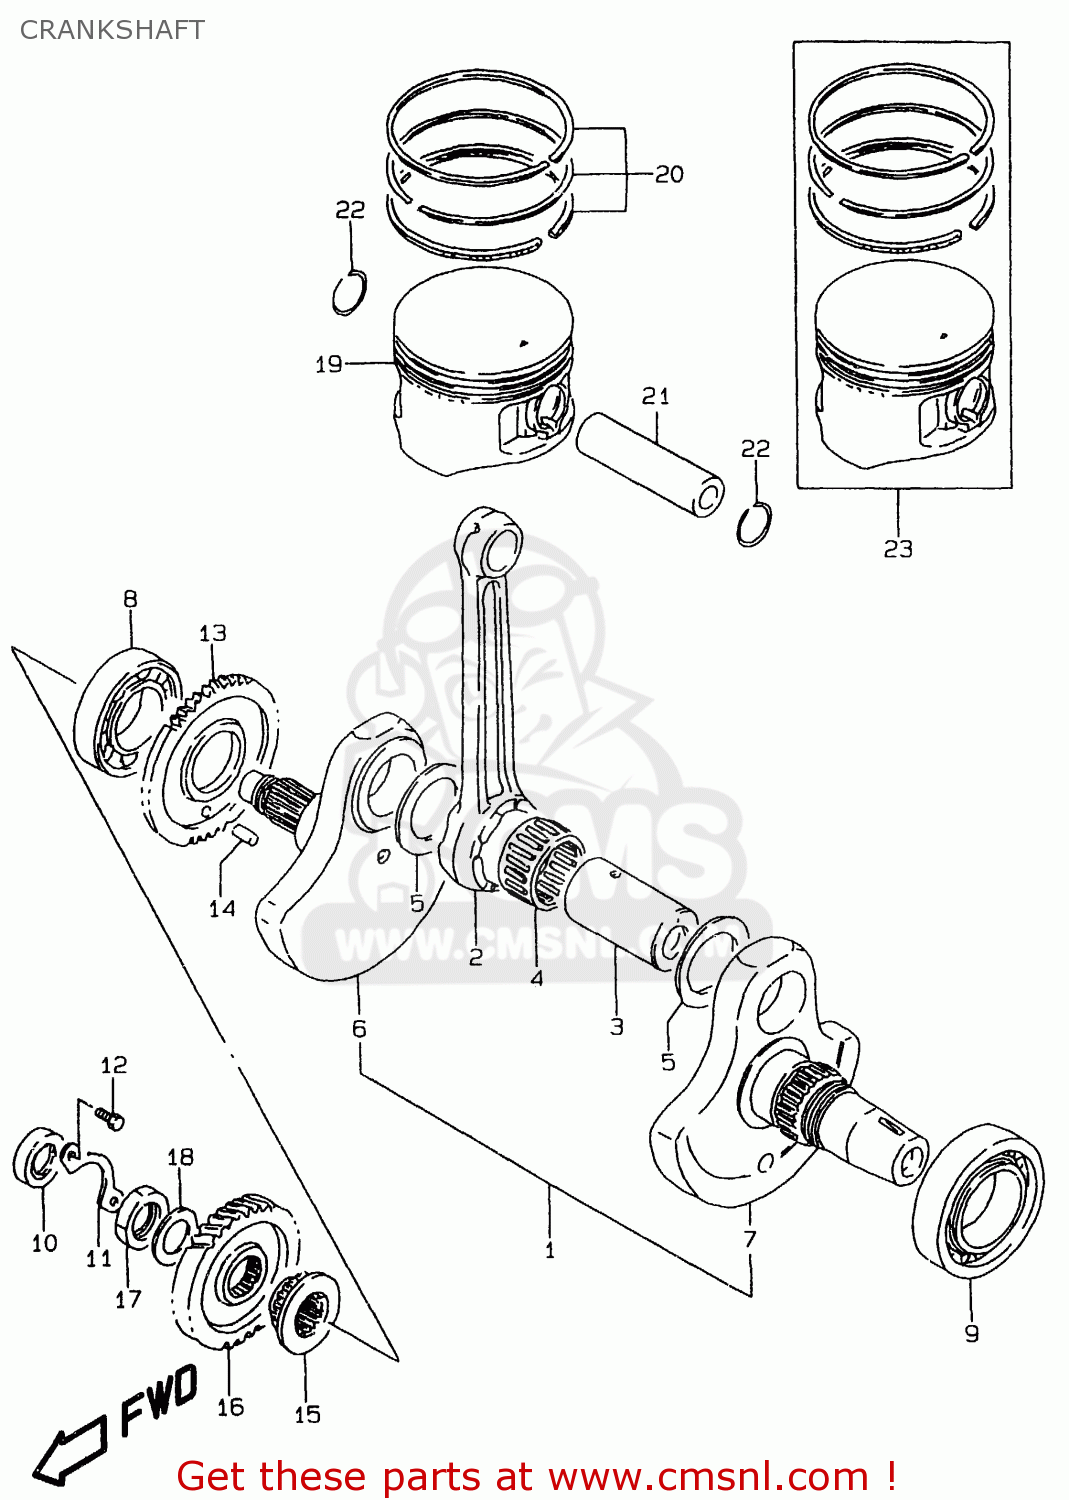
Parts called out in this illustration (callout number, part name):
1	CRANKSHAFT ASSY
2	ROD,CONNECTING
3	PIN,CRANK
4	BEARING(37X47X25)
5	WASHER(37X55X1)
6	CRANKSHAFT,R
7	CRANKSHAFT,L
8	BEARING(35X72X17)
9	BEARING(40X80X18)
10	SEAL,OIL(16X30X6)
11	RETAINER,CRANKSHAFT OIL SEAL,R
12	BOLT
13	GEAR,CRANK BALANCER DRIVE
14	PIN
15	SPROCKET,CAM CHAIN DRIVE
16	GEAR,PRIMARY DRIVE
17	NUT (20MM)
18	WASHER
19	PISTON (94.00MM)
20	RING SET,PISTON
21	PIN,PISTON
22	CIRCLIP
23	PISTON SET(OS:0.5)
